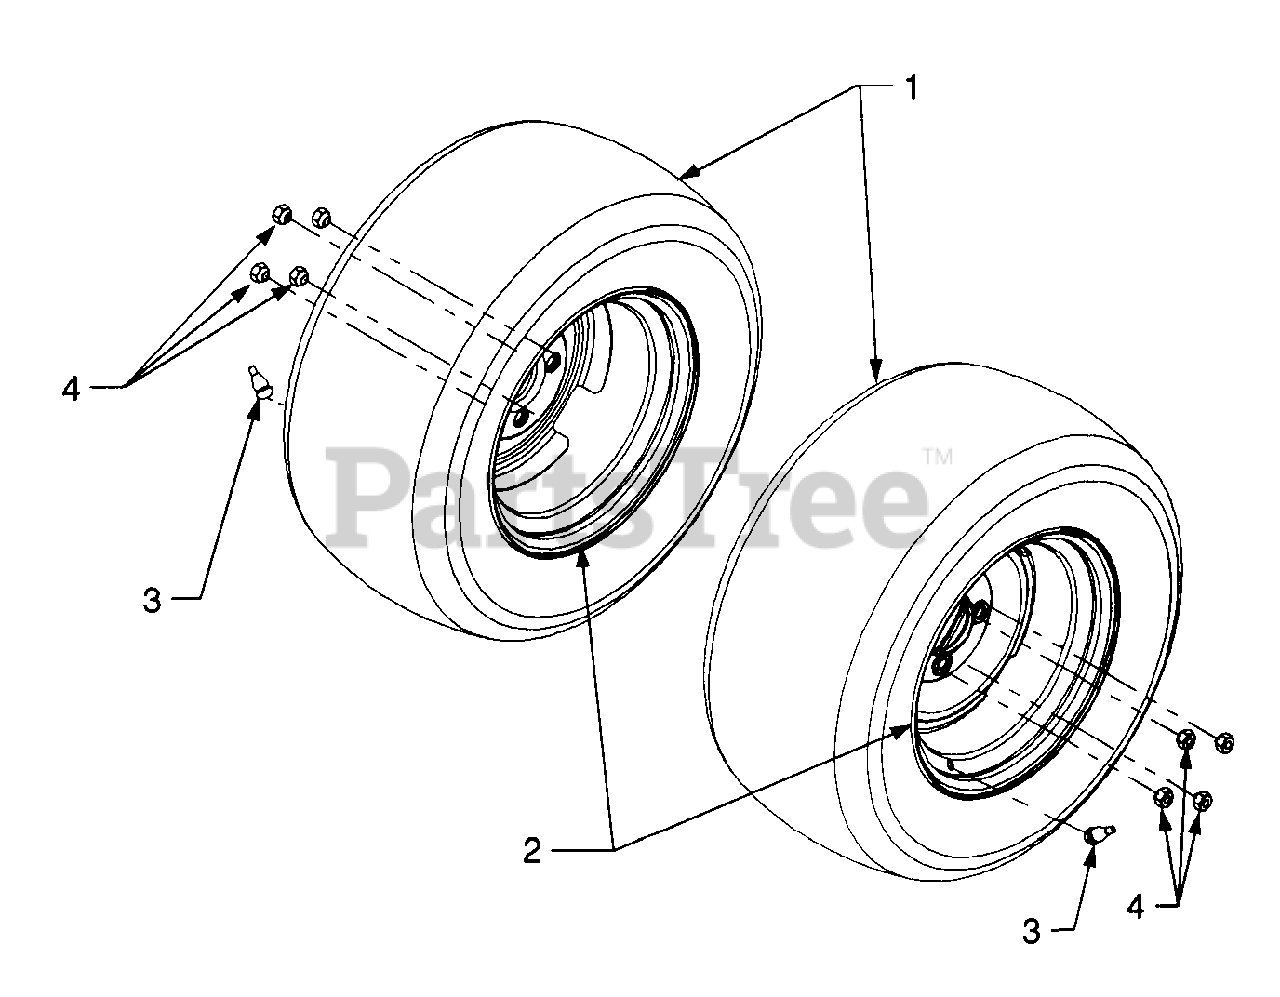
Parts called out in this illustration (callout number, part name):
1	Tire, Turf, 24 x 10.5 - 12
2	Rim Assembly, Wheel
3	Valve, Tubeless Air
4	Lug Nut, 7/16-14
